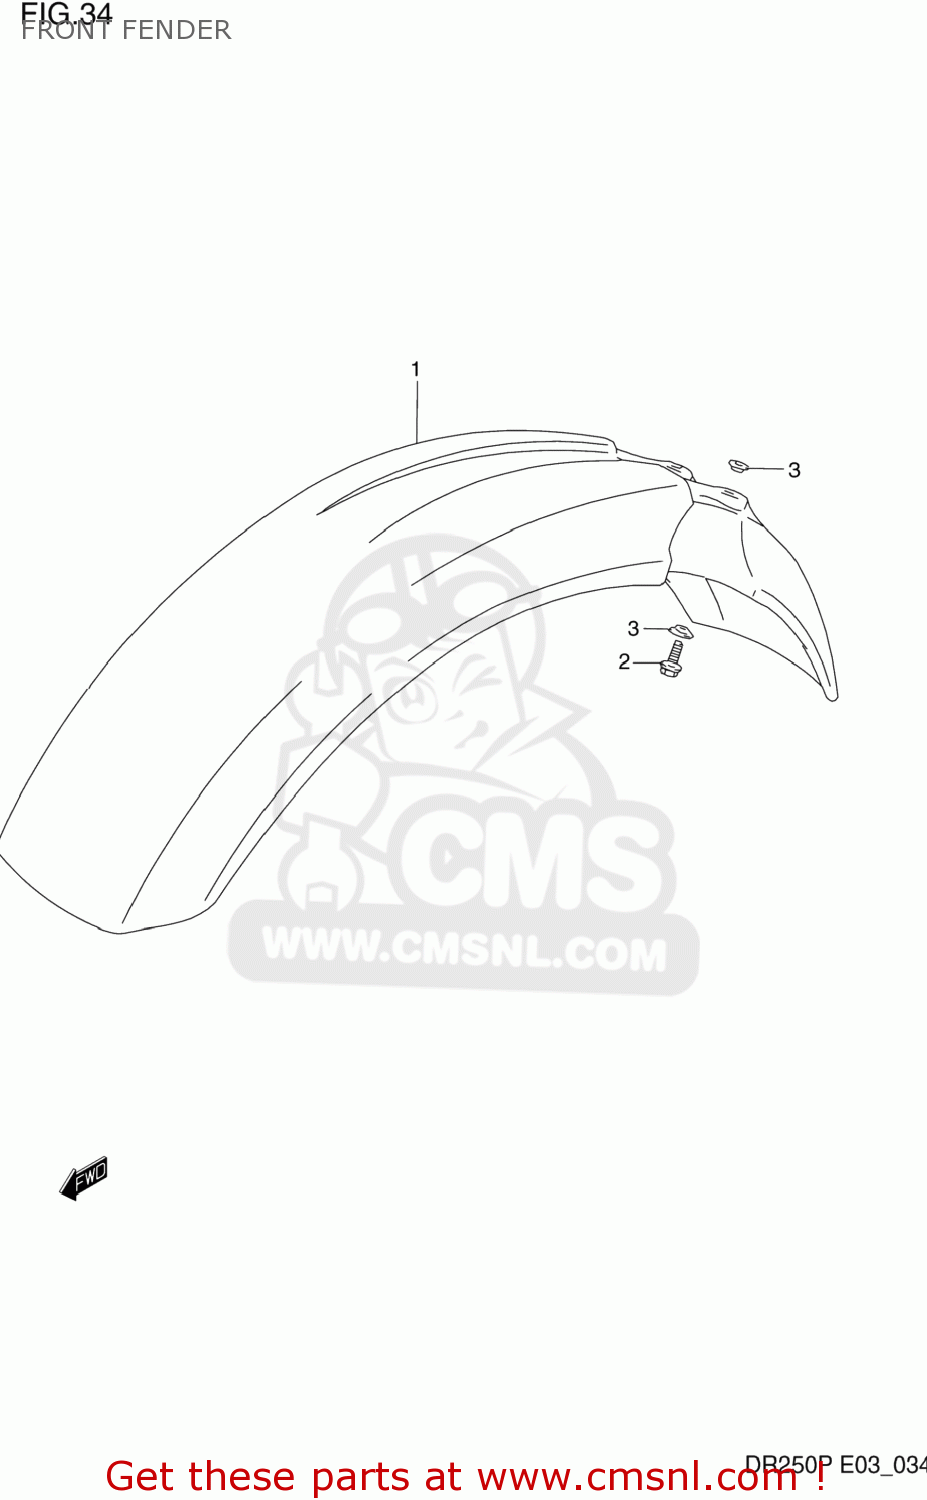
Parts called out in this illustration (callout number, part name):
1	FENDER,FR
2	BOLT 6X16
3	WASHER
